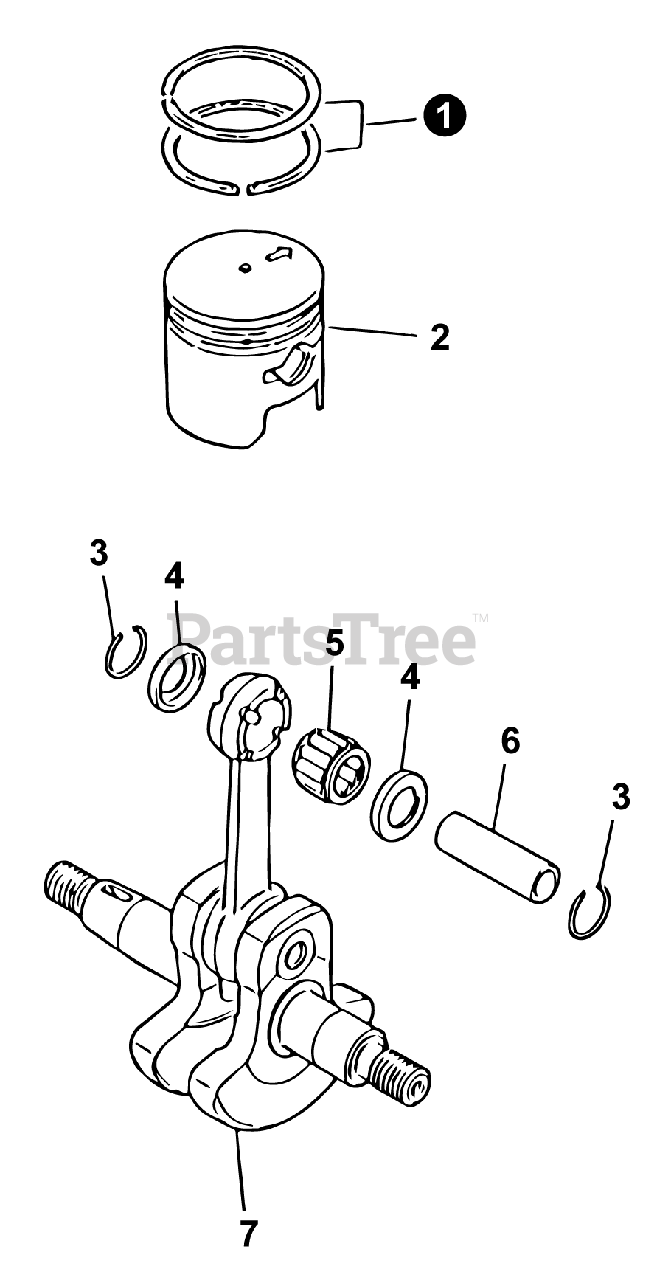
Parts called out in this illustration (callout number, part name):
1	RING, PISTON
2	PISTON
3	RING, SNAP
4	WASHER, THRUST 11
5	BEARING, NEEDLE 11
6	PIN, PISTON
7	CRANKSHAFT ASSY
